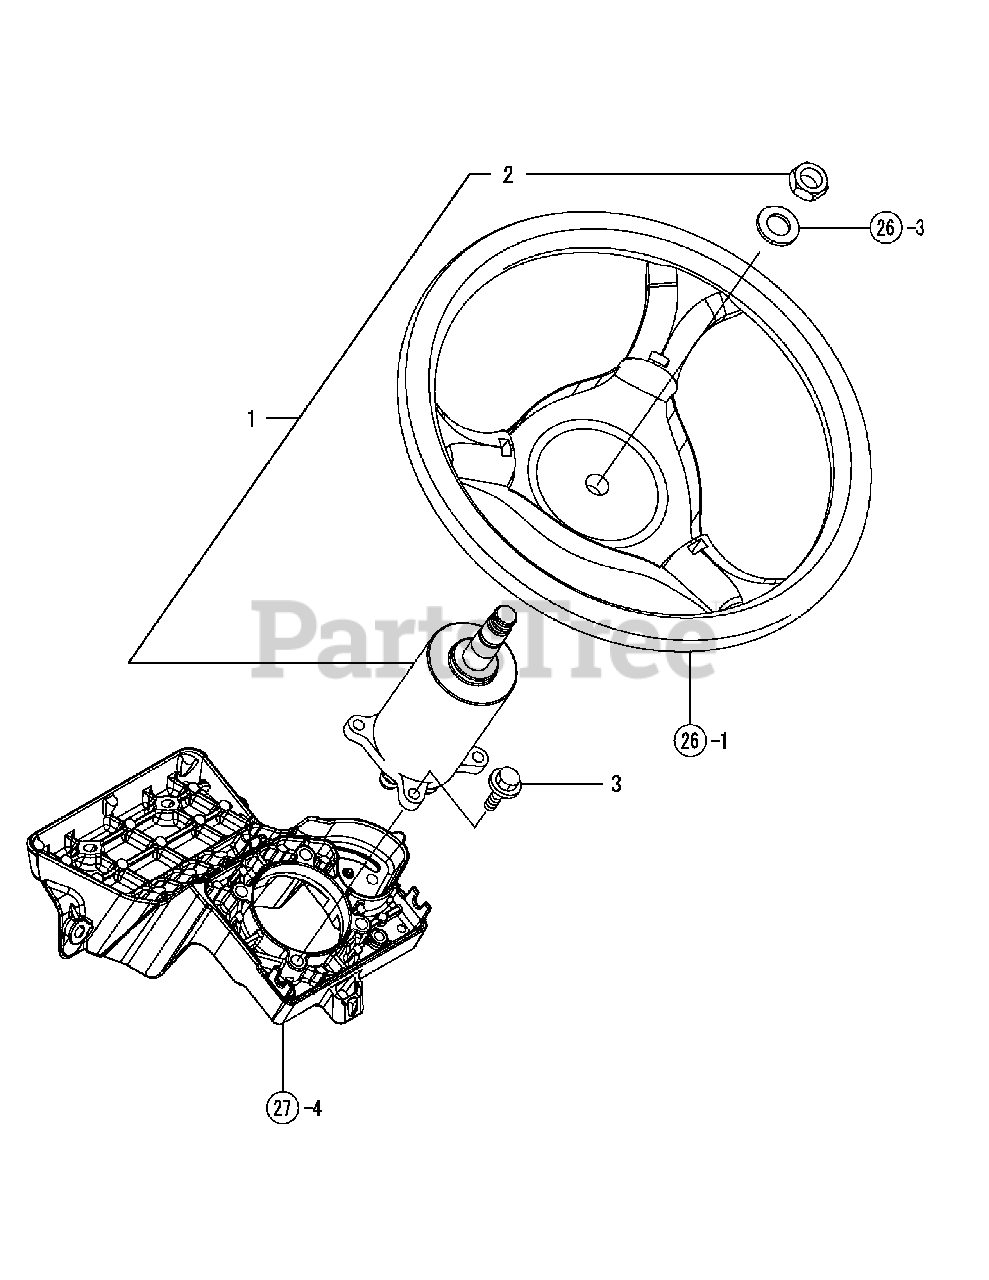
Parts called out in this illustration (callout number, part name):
1	VALVE ASSY, STEERING
2	NUT, 5/8-18 UNF
3	BOLT M 8X 30 PLATED
